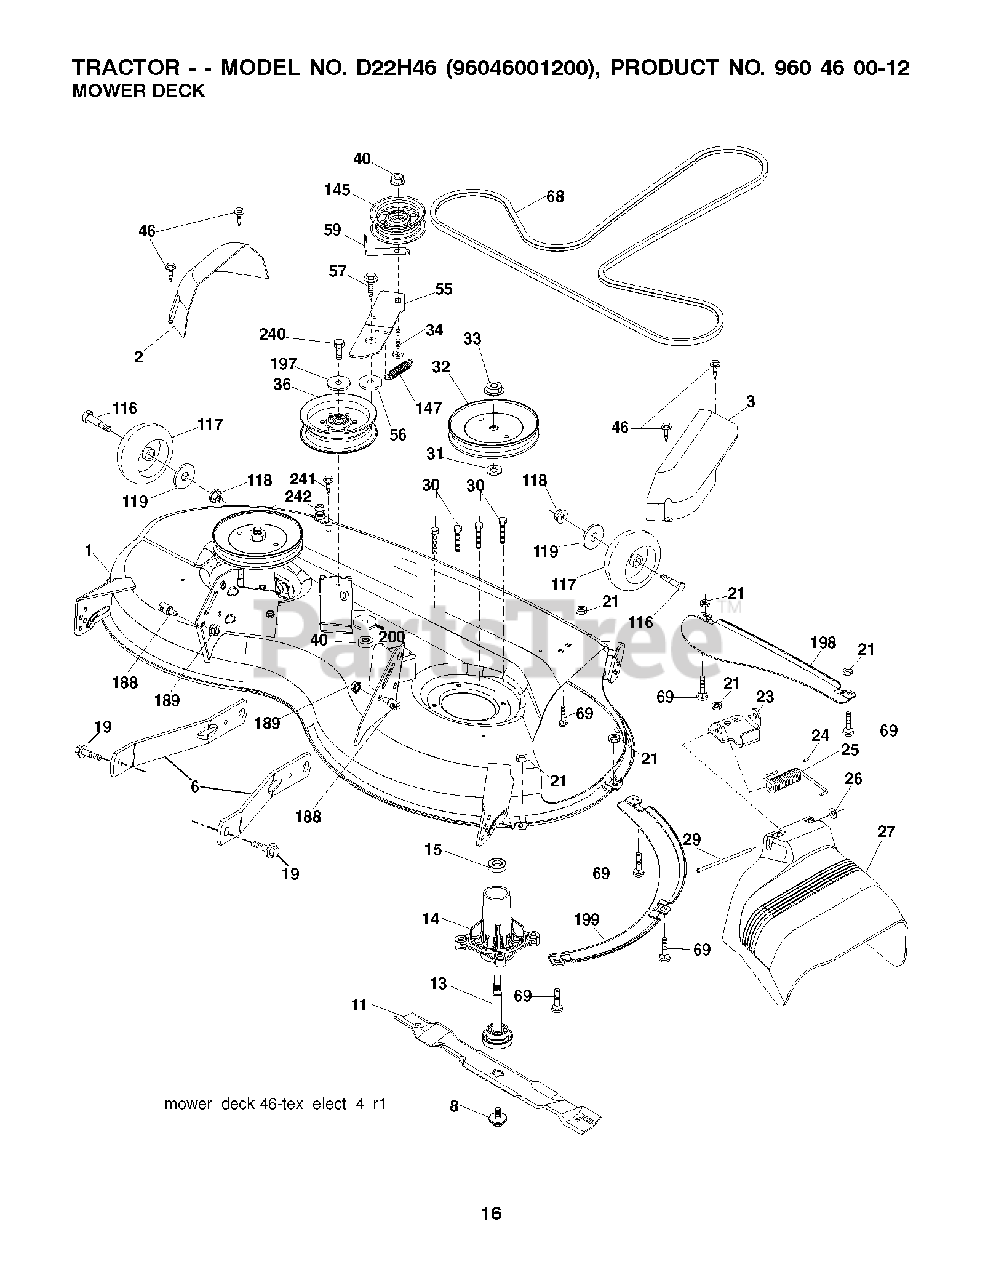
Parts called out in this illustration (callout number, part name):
1	DECK.WELDMENT.46"4GW.WHL.MS666
2	COVER.MANDREL.LH.46"
3	COVER.MANDREL.RH.46"
6	ARM.SUSPENSION.MOWER.R
8	BOLT.WASHER.ASM.7/16-2
11	BLADE.MOWER.46".HI.LIFT
11	BLADE, 46" MULCH
13	SHAFT.ASM.MDRL.N/GREASE.38
14	HOUSING.MANDREL.4PT.
15	BEARING
19	BOLT.SHOULDER
21	LOCKNUT
23	BRKT.DEFLECTOR.38"2005+
24	CAP-SLEEVE LT
25	SPRING.TORSION.DEFLECT
26	NUT PUSH M
27	SHIELD.DEFLECTOR.MOWER.46"BLAC
29	ROD.HINGE
30	SCREW, WASHER HEAD
31	WASHER.SPACER.MANDREL
32	PULLEY.MANDREL.5.438.PD
33	NUT.FLANGE.LOCK.TOP
34	BOLT.3/8-16X1.50
36	PULLEY.IDLER.2006
40	NUT LOCK FLG 3/8-16 UNC
46	SCREW.1/4-20X5/8
55	IDLER.ARM
56	SPACER.RETAINER
57	SCREW 3/8-16X1
59	GUARD, BELT
62	BOLT-HEX EAK
68	V-BELT
69	BOLT
116	Shield Bolt, A 2.41 B 1.66
117	WHEEL.GAGE.HALF.SPOKED
118	LOCKNUT
119	WASHER
145	PULLEY.IDLER.48"PRIMARY
147	SPRING.MOWER.DRIVE.ELECTRIC
188	STUD.FASTNER.W/ANTI-ROTATE
189	NUT LOCK HEX FLANGE 5/16-18
197	WASHER
198	BAFFLE CENTER FRONT
199	BAFFLE FRONT RH
200	WASHER.13/32 X 1 X 1/2.11GUARD
241	SCREW.TT.#10-32X.5.3/8.FLANGE
242	PORT.WASHOUT
